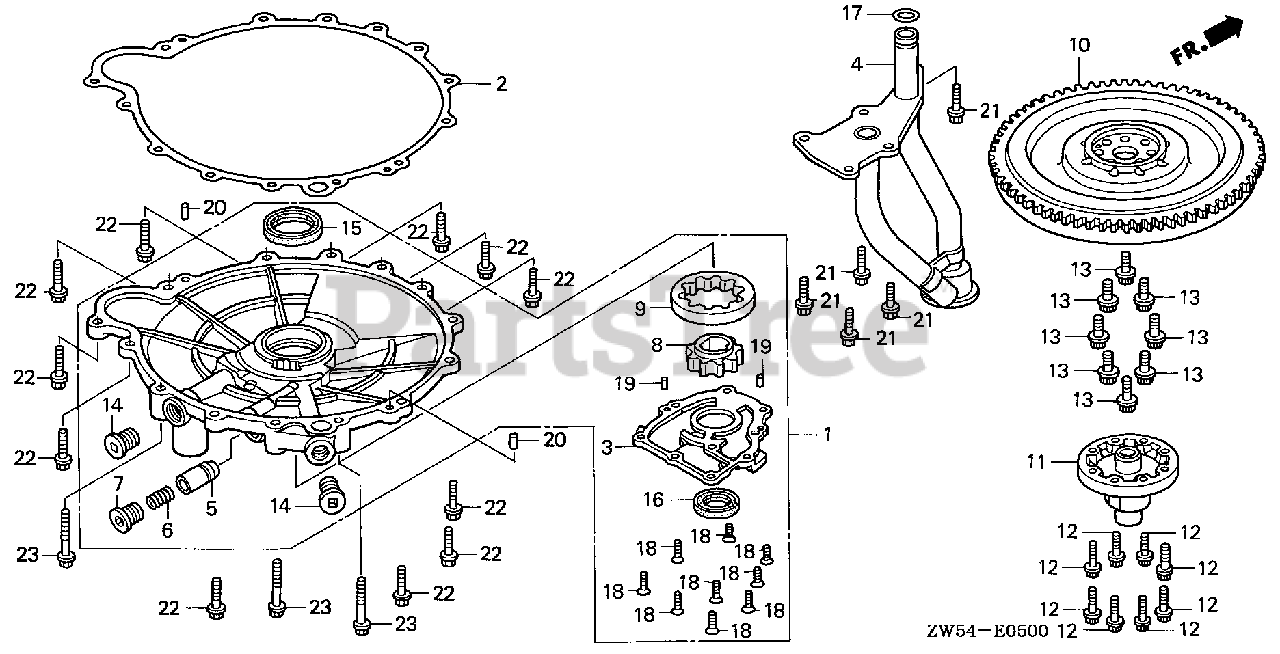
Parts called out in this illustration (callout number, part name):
1	PUMP ASSY., OIL
2	GASKET, OIL PUMP BODY
3	COVER, OIL PUMP
4	STRAINER, OIL
5	VALVE, RELIEF
6	SPRING, RELIEF VALVE
7	BOLT, SEALING (18MM)
8	ROTOR, OIL PUMP (INNER)
9	ROTOR, OIL PUMP (OUTER)
10	FLYWHEEL *TBLACK* (BLACK)
11	BOSS, FLYWHEEL
12	BOLT, SPECIAL (8MM)
13	BOLT (12MM)
14	BOLT, SEALING (22MM)
15	OIL SEAL (46X60X9)
16	OIL SEAL (31X46X7) (NOK)
17	O-RING (20.6X2.6)
18	SCREW, FLAT (6X16)
19	PIN, DOWEL (5X8)
20	PIN, DOWEL (6X10)
21	BOLT, FLANGE (8X20)
22	BOLT, FLANGE (8X30)
23	BOLT, FLANGE (8X50)
